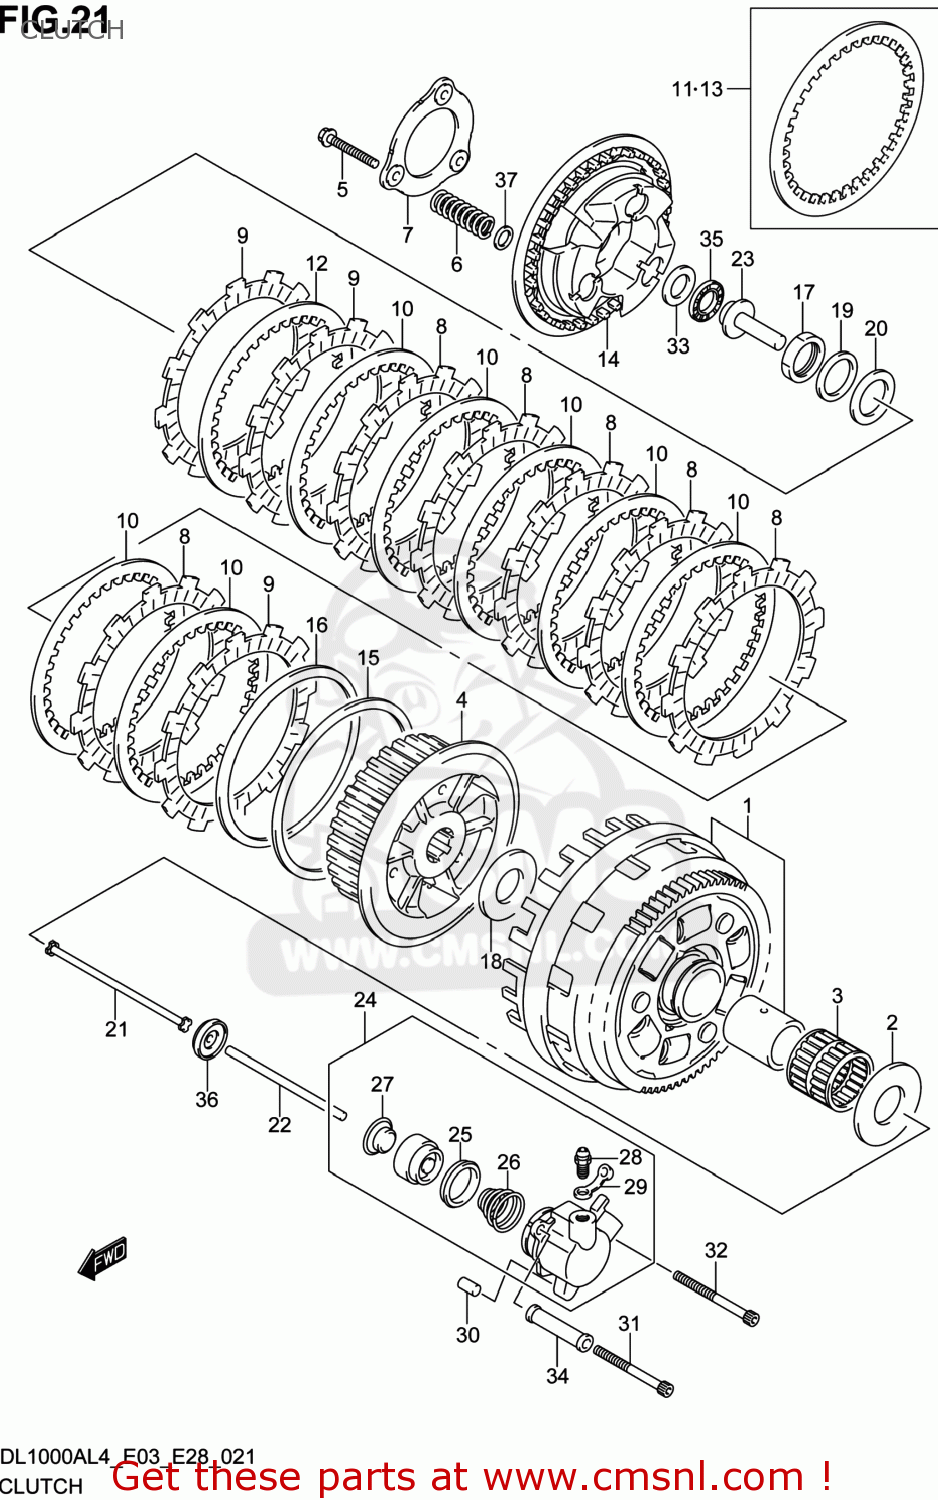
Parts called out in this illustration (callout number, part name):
1	GEAR ASSY,PRIMARY DRIVEN
2	WASHER(25X52X2.5)
3	BEARING(35X40X39.8)
4	HUB,CLUTCH SLEEVE
5	BOLT,CLUTCH SPRING
6	SPRING,CLUTCH
7	PLATE,STOPPER
8	PLATE,CLUTCH DRIVE NO.1 (NAS)
9	PLATE,CLUTCH DRIVE NO.2 (NAS)
10	PLATE,CLUTCH DRIVEN NO.1(T:2.0 (NAS)
11	PLATE,CLUTCH DRIVEN NO.2(T:2.3 (NAS)
12	PLATE,CLUTCH DRIVEN NO.2 (NAS)
13	PLATE,CLUTCH DRIVEN NO.3 (NAS)
14	DISC,CLUTCH PRESSURE
15	SEAT,WAVE WASHER
16	WASHER,CLUTCH PLATE WAVE
17	NUT
18	WASHER(25X50X2.5)
19	WASHER
20	SHIM(25X38X1)
21	ROD,CLUTCH
22	ROD,CLUTCH PUSH,L
23	PIECE,CLUTCH PUSH
24	CYLINDER,CLUTCH RELEASE
25	CUP
26	SPRING,CLUTCH CYLINDER
27	COVER,DUST
28	BLEEDER
29	CAP,BLEEDER
30	PIN
31	BOLT
32	BOLT
33	WASHER(15.5X28X1)
34	SPACER,CL RLSE CYL
35	BEARING(15X28X2)
36	SEAL,OIL(6X34X10.5)
37	SEAT,CLUTCH SPRING
